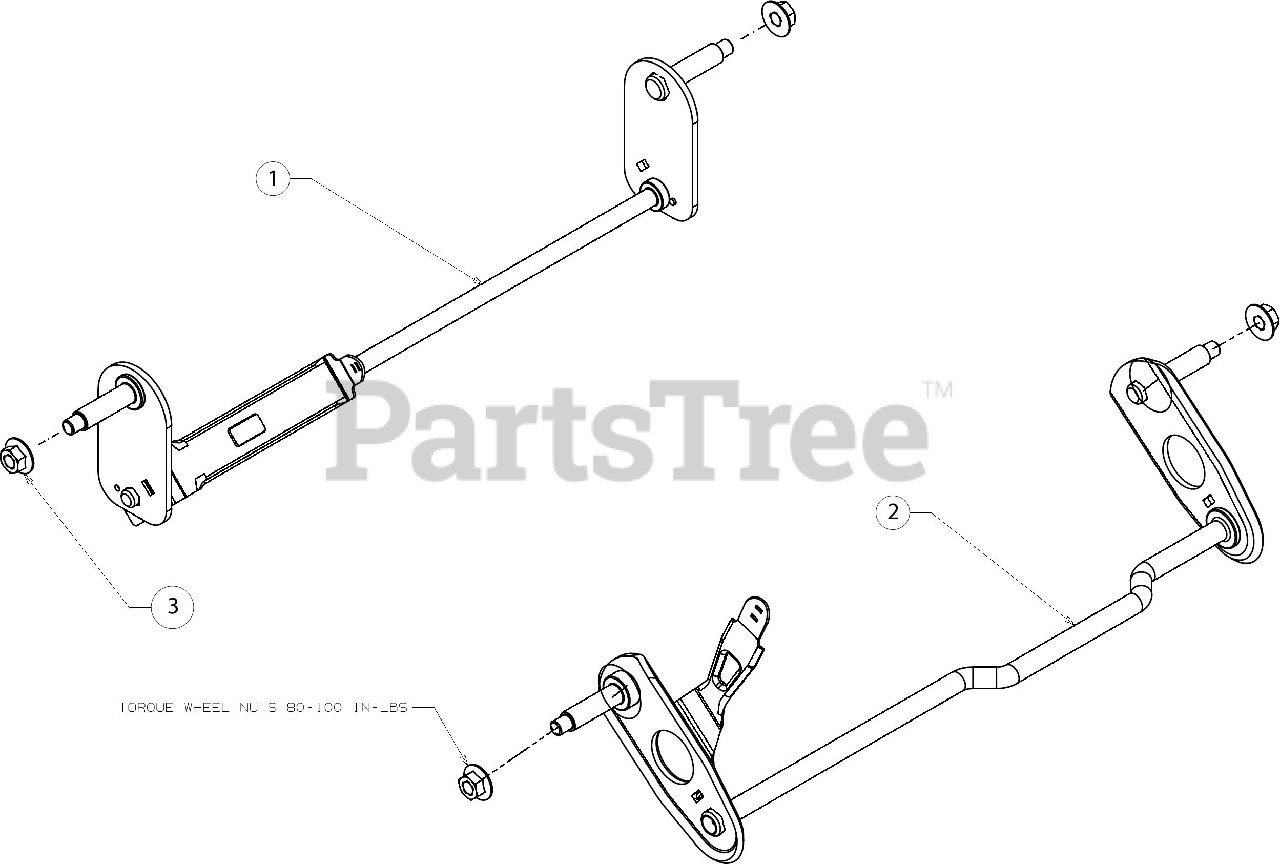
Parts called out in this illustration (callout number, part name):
1	11" REAR AXLE ASSEMBLY
2	8" FRONT AXLE ASSEMBLY
3	FLANGE LOCK NUT
